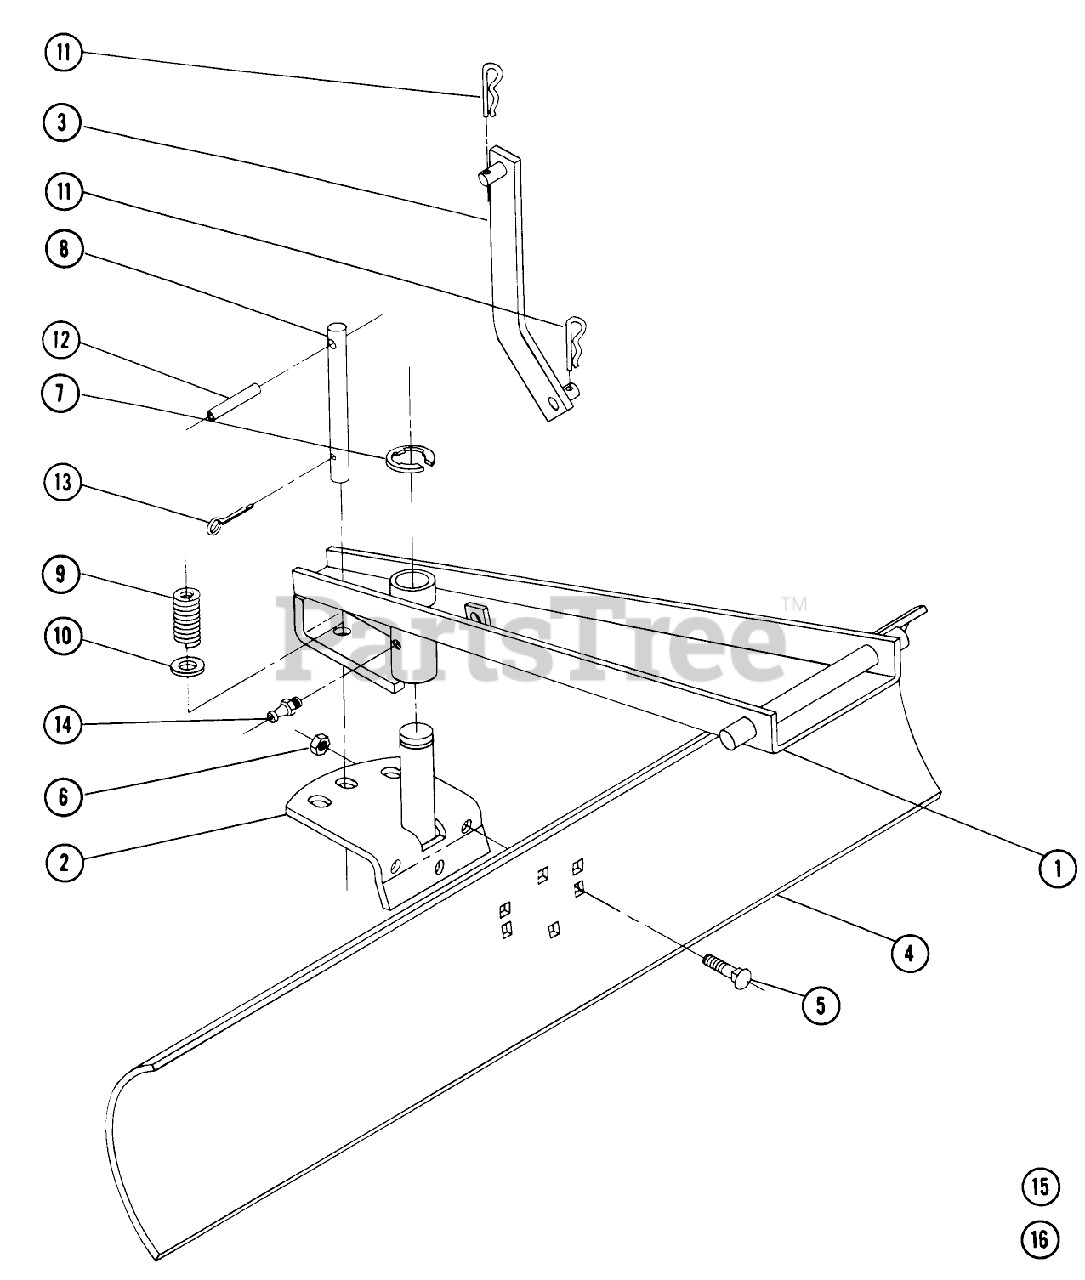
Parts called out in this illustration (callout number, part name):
1	Ass-y. Frame
2	Ass-y. Blade Support
5	Bolt 3/8-16 x 1
6	3/8-16 E.S.
7	E RING
8	Pin-Pawl
9	Spring-Compression
10	Washer, 5/8
11	Hairpin
13	Cotter Pin
15	Decal-"Safety First"
